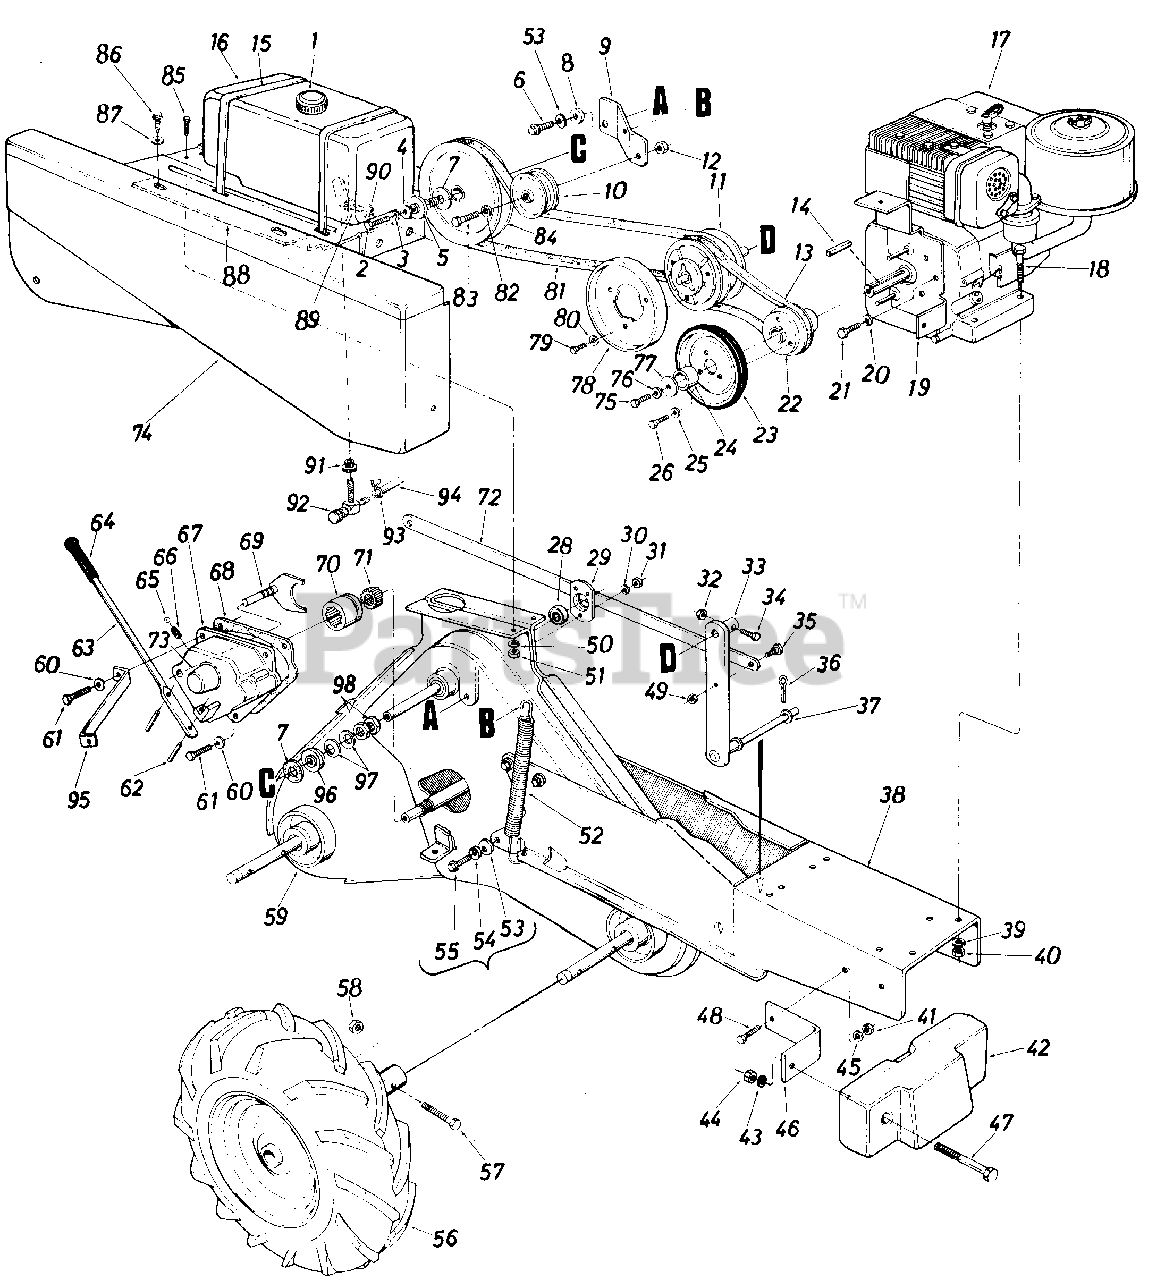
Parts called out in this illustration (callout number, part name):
1	Gas Cap
2	Hex L-Bolt 5/16-24 x 1.5" Lg.
3	L-Wash. 5/16" I.D.*
4	Fl-Wash. 5/16" I.D. x 1.125" O.D.
5	Friction Disc Ass'y.
6	Hex Bolt 3/8-24 x 1.25" Lg.
7	Friction Pad
8	Shoulder Spacer
9	Idler Bracket
10	Fl-Idler 2.75" Dia.
11	Variable Speed Ass'y.
12	Hex Ins. L-Nut 3/8-16 Thd.
13	"V"-Belt 5/8" x 27.0" Lg.
14	Sq. Key 1/4" x 1.50" Lg.*
15	Cable Tie
16	Gas Tank
17	Engine
18	Hex Bolt 5/16-18 x 1.75" Lg.*
19	Belt Cover Support Ass'y.
20	Internal L-Wash. 1/2" I.D.
21	Hex Bolt 1/2-20 x .75" Lg.
22	Engine Pulley Ass'y.
23	Friction Wheel Ass'y.
24	Spacer
25	L-Wash. 5/16" I.D.*
26	Hex Bolt 5/16-18 x .50" Lg.*
28	Ball Bearing
29	Bearing Housing 1-3/8" O.D.
30	L-Wash. 1/4" I.D.*
31	Hex Nut 1/4-28 Thd.*
32	Hex Ins. L-Nut 1/4-20 Thd.
33	Variable Speed Brkt. Ass'y.
34	Hex Bolt 1/4-20 x 1.25" Lg.*
35	Shld. Bolt 1/2" Dia. x .25" Lg.
36	Cotter Pin 118" Dia. x 1.0" Lg.*
37	Fl-Wash. .686" I.D. x 1.25" O.D.
38	Frame Ass'y.
39	L-Wash. 5/16" I.D.*
40	Hex Nut 5/16-18 Thd.*
41	Hex Cent. L-Nut 3/8-24 Thd.
42	Weight
43	Fl-Wash. .50" I.D. x 1.0" O.D.
44	Hex Nut 1/2-13 Thd.*
45	L-Wash. 3/8" I.D.*
46	Weight Mtg. Brkt.
47	Hex Bolt 1/2-13 x 4.50" Lg.*
48	Hex Bolt 3/8-24 x 1.00" Lg.*
49	Hex Ins. L-Nut 3/8-16 Thd.
50	L-Wash. 1/4" I.D.*
51	Hex Cent. L-Nut 1/4-28 Thd.
52	Spring Idler Bracket
53	Belleville Wash. 3/8" I.D.
54	L-Wash. 3/8" I.D.*
55	Hex Self-Tap Scr. 3/8-16 x .75" Lg.
56	Wheel Ass'y. Comp.-R.H.
57	Hex Bolt 3/8-24 x 1.25" Lg.
58	Hex Ins. L-Nut 3/8-24 Thd.
59	Chain Case Ass'y. Comp.
60	L-Wash. 5/16" I.D.*
61	Hex Tap Tite Scr. 5/16-18 x .75" Lg.
62	Headed Spiral Pin 3/16 x 13/16" Lg.
63	Engagement Lever
65	Ball Detent .250" Dia.
66	Compression Spring
67	Shift Housing-R.H.
68	Gasket-Shift Housing
69	Shift Yoke Ass'y.-R.H.
70	Clutch Dog
71	Clutch Dog Driver
72	Control Brkt.
73	Bearing
74	Shroud Belt Cover
75	Hex Bolt 7/16-20 x 1.00" Lg.
76	L-Wash. 7/16" I.D.
77	Fl-Wash. .44 I.D. x 1.38" O.D.
78	Friction Disc
79	Hex Bolt 1/4-28 x .50" Lg.
80	L-Wash. 1/4" I.D.
81	"V"-Belt 5/8" x 51" Lg.
82	L-Wash. 3/8" I.D.
83	Hex Bolt 3/8" x 1.50" Lg.
84	Input Pulley-Chain Case
85	Hex Bolt 1/4-28 x .62" Lg.
86	Hex Wash. Hd. Self-Tap Scr.
87	Fl-Wash. 1/4" I.D.
88	Tank Mounting Brkt.
89	Hex Bolt 5/16-18 x .75" Lg.
90	L-Wash. 5/16" I.D.
91	Bushing-Gas Line
92	Shut-Off Valve
93	Clamp Gas Line
94	Gas Line 141/2" Lg.
95	Brace
96	Floating Disc
97	Spring Bell-Wash.
98	Hex Jam Nut 1.0-14
